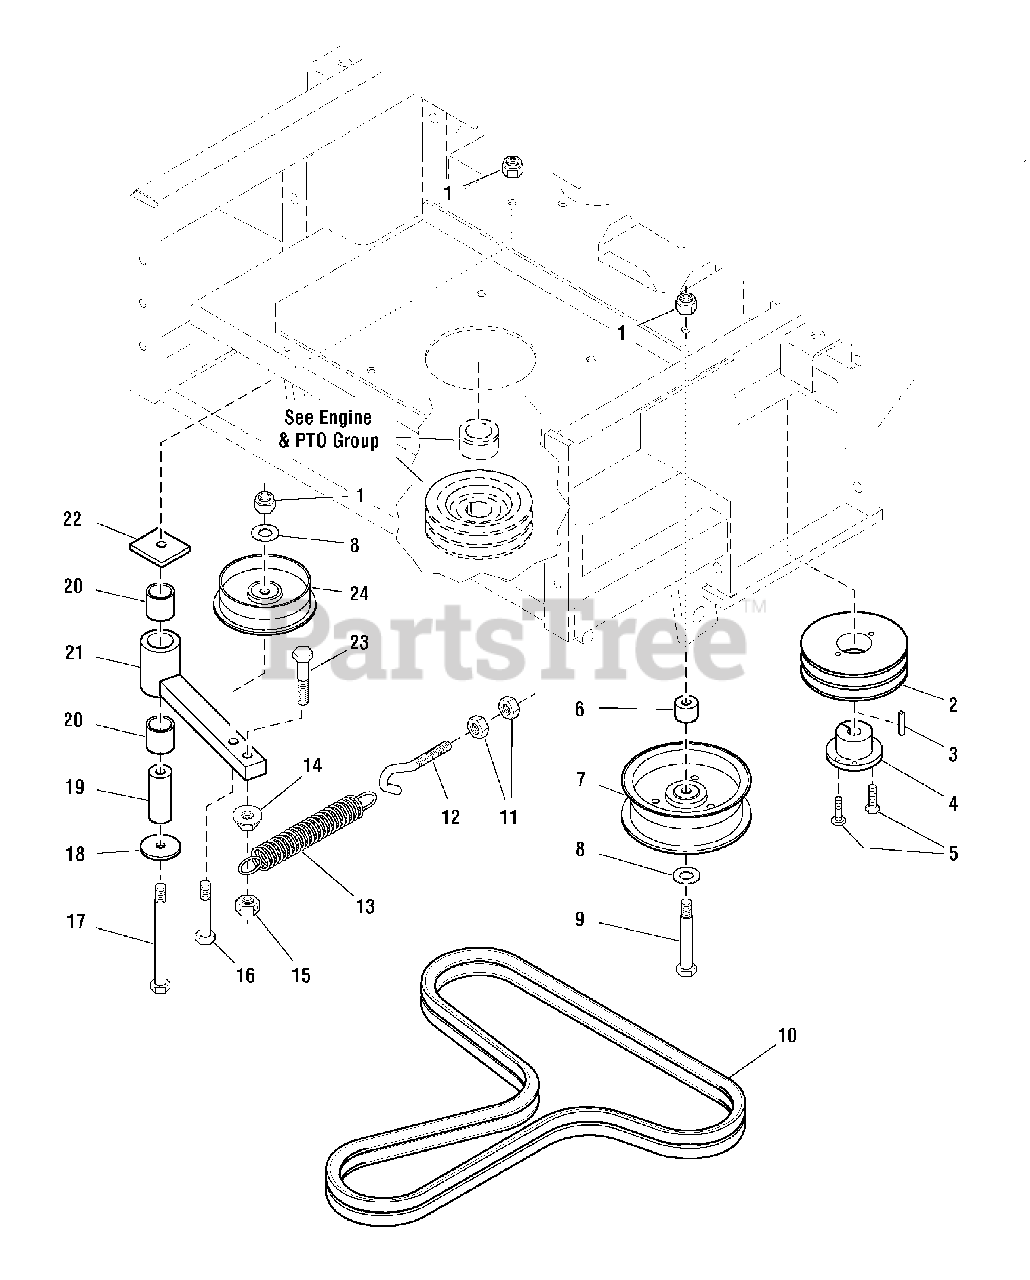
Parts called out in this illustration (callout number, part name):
1	NUT, Hex, Nylon Lock, 3/8-16
2	PULLEY, Pump Drive
3	KEY, 5mm x 25mm
4	BUSHING, Tapered Hub
5	BOLT, 1/4-20 X 1", GD
6	SPACER, .39 x 1.00 x .79
7	PULLEY, Idler
8	WASHER, 3/8
9	CAPSCREW, Hex Hd, 3/8-16 x 2-3/4
10	BELT, BANDED A-SEC, 64.76EL, POLY, RAW EDGE
11	NUT, Hex, 3/8-16
12	EYE BOLT, 3/8-16 X 5" " EYE
13	SPRING, Extension, Swivel End
14	NUT, Hex, Serrated Flange, 3/8-16
15	NUT, Hex, Side Lock, 3/8-16
16	CAPSCREW, Hex Hd, 3/8-16 x 2-1/4
17	CAPSCREW, Hex Hd, 3/8-16 x 4
18	WASHER, 3/8 x 1-3/4
19	SHAFT, Idler Pivot
20	BUSHING, Brass
21	WELD, ARM, PUMP DRIVE IDLER - BLK
22	SPACER, Idler Pivot
23	CAPSCREW, Hex Hd, 3/8-16 x 1-3/4
24	PULLEY, Idler (Single Flange)
